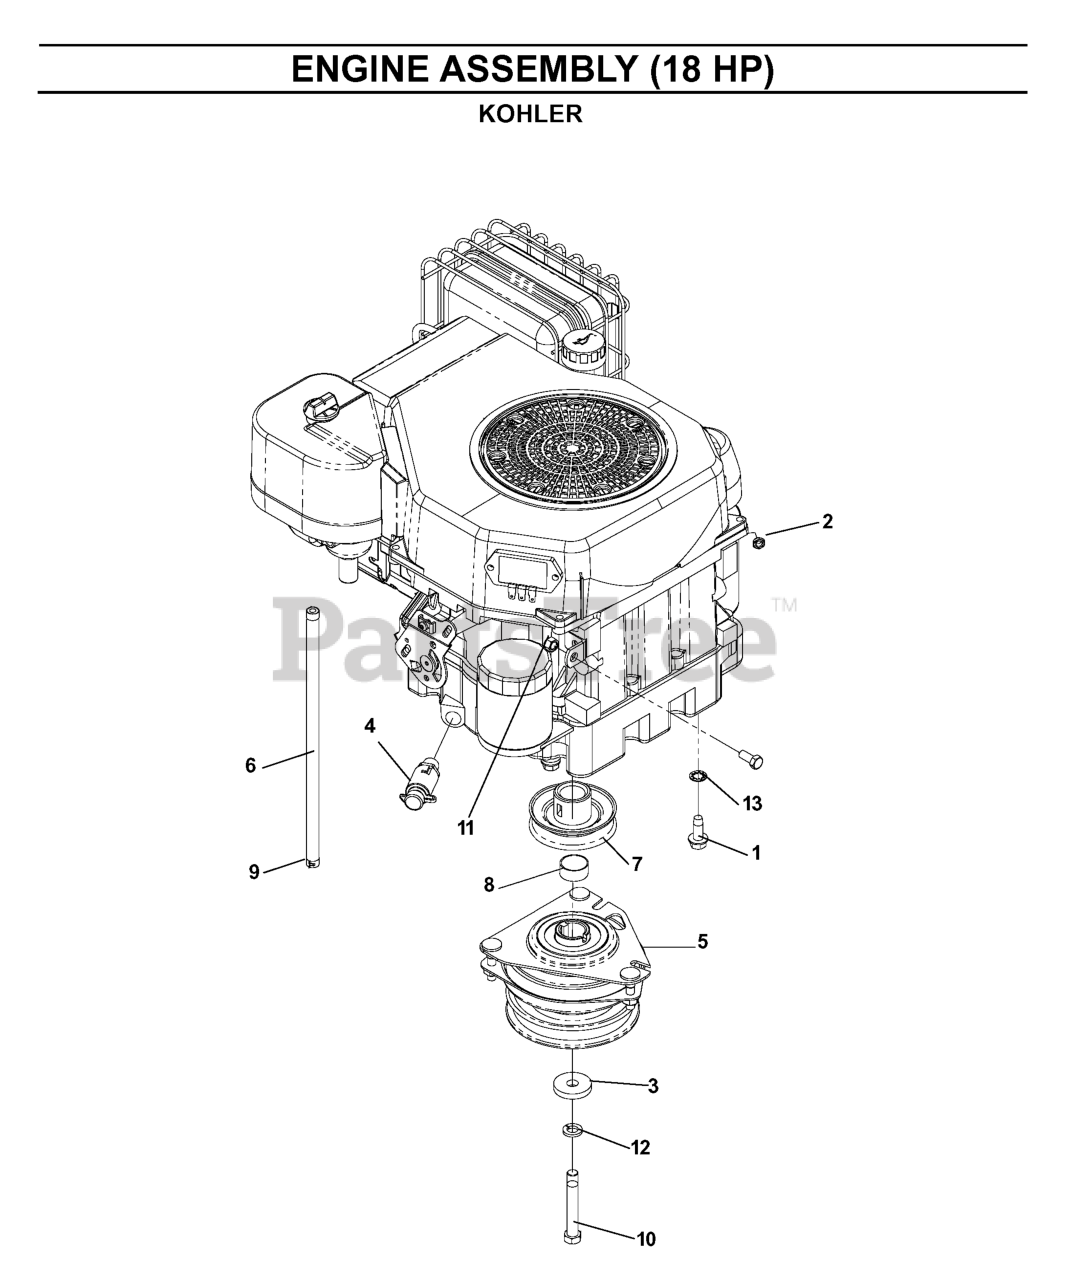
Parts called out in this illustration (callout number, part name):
1	BOLT 3/8-16 X 1.0
2	JAM NUT 1/4C (2 2 PW01)
3	CLUTCH, WASHER
4	OIL DRAIN FITTING
5	CLUTCH 90 FT/LB OGURA
6	FUEL LINE 5"
7	PULLEY, ENGINE
8	SPACER, ENGINE - PULLEY
9	HOSE CLAMP
10	HEX SCREW 7/16-20 X 3
11	NUT 3/8C CENTERBLOCK
12	WASHER 7/16 LOCK
13	WASHER, 3/8 ITLW ZN
